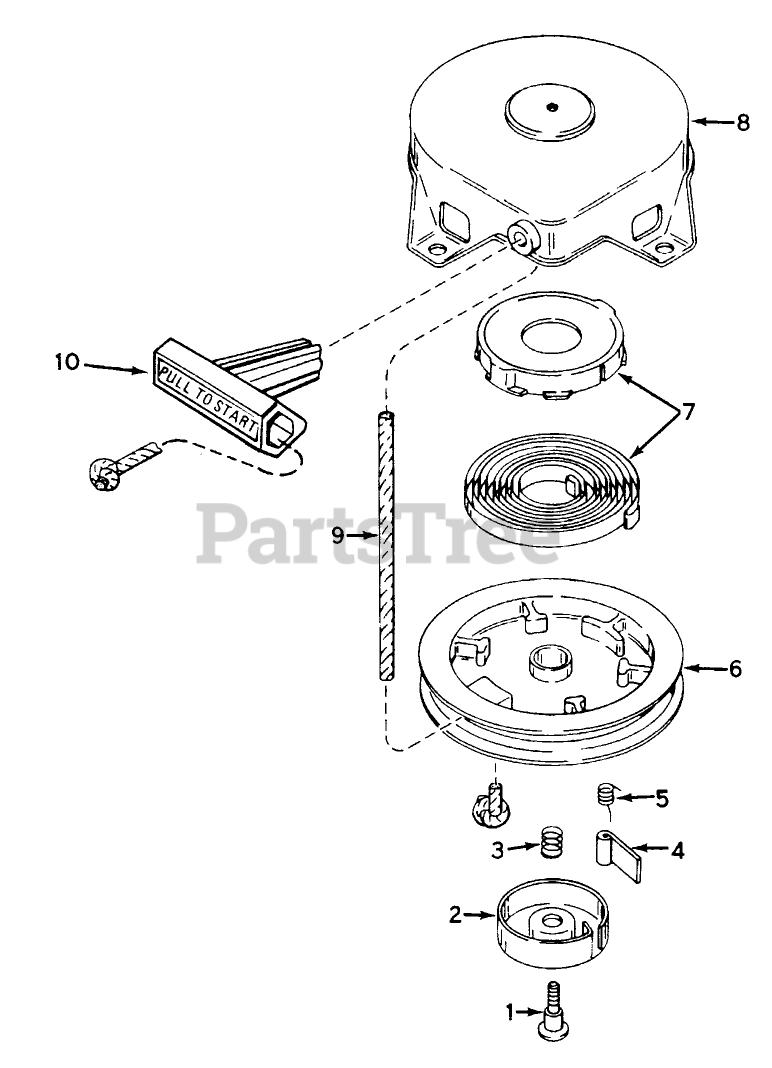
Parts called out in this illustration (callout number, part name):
1	Screw
2	Retainer
3	Spring-Brake
4	Dog-Starter
5	Spring-Dog
6	Pulley
7	Spring Keeper Assy
8	Housing Assy., Starter (Incl. Ref. #1)
9	Rope-Starter
10	Handle-Starter
